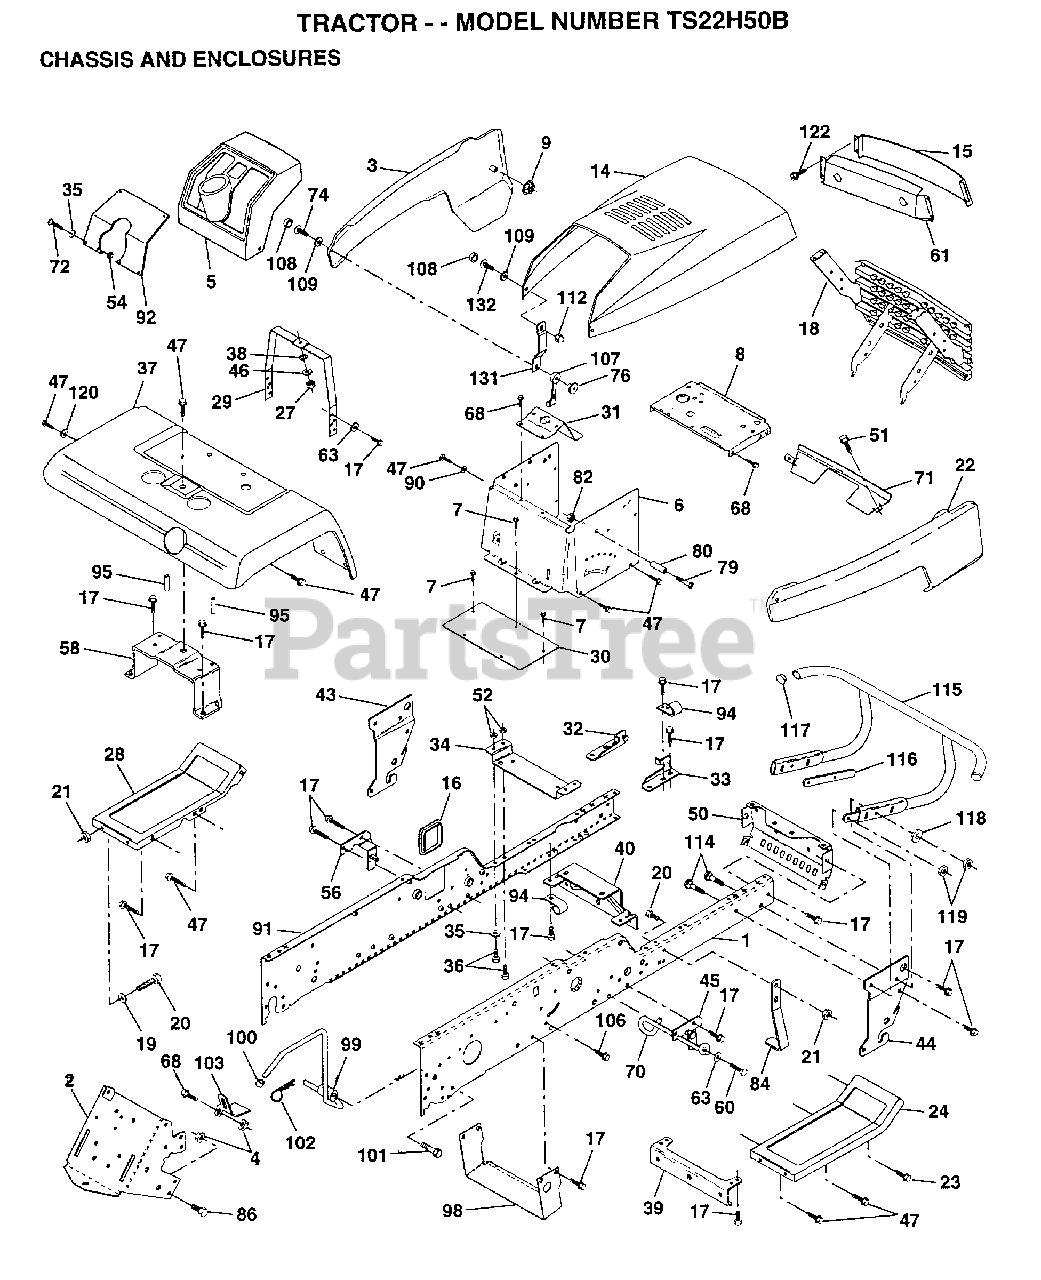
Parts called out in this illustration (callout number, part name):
1	"RAIL,FRAME RH"
2	DRAWBAR GT
3	PANEL ASM SIDE LH
4	NUT.7/16
5	DASHBOARD BLACK
6	"DASH AS.,LOWER"
7	SCREW
8	SUPPORT.DASH.BTRY
9	PAL NUT LT
15	LENS.BAR.CLEAR
17	SCREW
19	COVER ACCESS
19	WASHER
20	BOLT
23	SCREW GTV
24	FOOTREST.RH.LT/GT
28	FOOTREST.LH.LT/GT
29	DASH.SUPT.YP/HUSQ
30	SADDLE.HYDRO.95
31	BRAKET.SUPT.STEER
32	BRACKET ASM FRAME
33	BRACKET ASM FRAME
34	BRACKET.ENG.SUPT.
35	WASHER
36	BOLT
37	FENDER.PNT.
38	WASHER PM
39	BRACKET.AXLE.FRT.
40	HARNESS.IGN.FEND.
43	BRACKET.SUS.FT.LH
44	BRACKET.SUS.FT.RH
46	LOCKWASHER
47	SCREW LT
50	"BRKT CHASSIS,FRNT"
51	SCREW CRT
58	BRKT.ASM.FENDER
60	SCREW
61	BEZEL.ASM.
63	WASHER
68	SCREW LT
70	GUIDE.BELT.MID.SP
71	STRAP.GRILLE.PNT.
72	SCREW
74	SCREW
76	WELDNUT
79	SCREW
80	SPACER LT
84	STOP.OVER.CENTER
86	BOLT
90	LOCKWASHER
91	"RAIL,FRAME LH"
92	PLATE YP SLKSCR
94	CLIP GTV
95	NUT-PUSH YT
98	BRACKET SKID CHAS
99	ROD BYPASS
101	SCREW LT
102	RETAINER M
103	LOCK BYPASS BRKT
107	HOOD LATCH T
108	SNAP CAP LT
109	WASHER LT
112	ACORN NUT RB
114	BOLT.3/8-14X1.25
115	BUMPER.ASM
116	BRACKET.EXT.BUMP.
117	PLUG.PLASTIC
118	WASHER
120	WASHER HYT
131	BKT.SPT.HOOD/PANL
132	SCREW.10-24X3/8.
